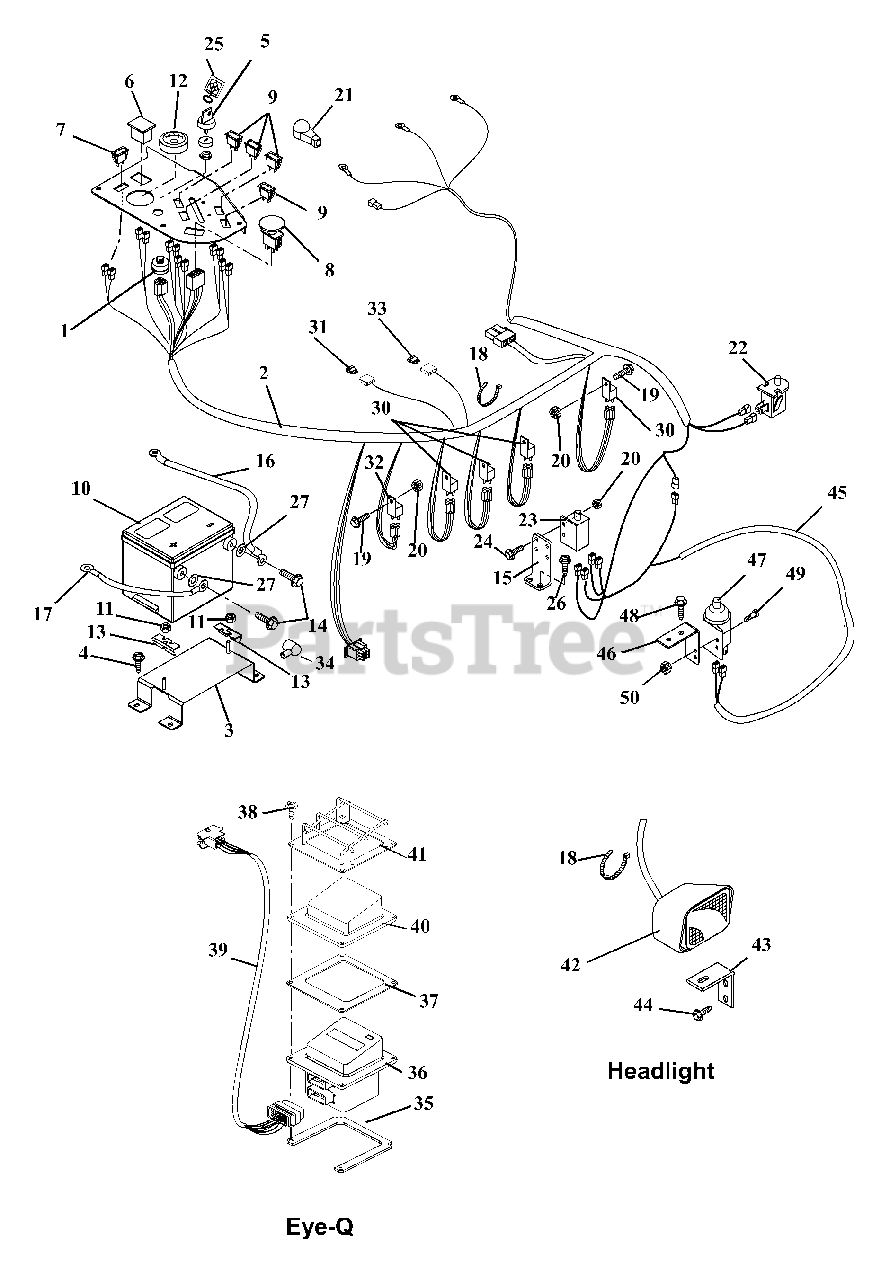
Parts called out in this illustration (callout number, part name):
1	SWITCH, IGNITION
2	HARNESS-MZ HORIZ L/C DIESEL
3	WMT, BATTERY SUPPORT
4	@SCR-TAP .38-16X.75 HWH TR YWZ
5	KEY, W/ SHIELD
6	HOUR METER - DIGITAL
7	SWITCH, 2 POLE/ROCKER
8	SWITCH, CLUTCH
9	LIGHT,INDICATOR
10	BATTERY, GROUP 70 450 CCA 35 A
11	@NUT-LK-TOP-FLG .31-18 YWZC
12	GAUGE, TEMPERATURE
13	BRKT, BATTERY HOLD-DOWN
14	BATT TERMINAL SCREW
15	MOUNT, SAFETY SWITCH
16	CABLE, POS BATT 4 GA X 45
17	CABLE, NEGATIVE BATTERY 49.00
18	CABLE TIE LG 5-1/2
19	@SCR-MCH 10-24X.75 HWH YWZC
20	@NUT-LK-NYL 10-24 W/INSRT YWZC
21	BOOT, EYELET TERMINAL
22	SWITCH- SNAP MTG N.O.
23	SWITCH- DOUBLE POLE N.O./N.O.
24	@SCR-MCH 10-24X.75 HWH YWZC
25	KEY CHAIN
26	@SCR-TAP .25-20X.50 HWH TR YWZ
27	@WSHR-FL-STL.38X.875X.083 YWZC
28	FUSE, ATO 15 AMP
29	DIODE, CONNECTOR SHELL
30	RELAY,SEALED W/DIODE
31	FUSE, ATO 30 AMP
32	Pre-Heat Timer
33	FUSE, ATO 60 AMP
34	BOOT, EYELET TERMINAL
35	SPACER, ENCLOSURE MTG. (BTM)
36	ASSY, EYE-Q
37	GASKET-EYE Q
38	SCR-MCH 10-24X1.0 SL PAN BLACK
39	HARNESS - EYE-Q
40	GUARD, ELEMENT
41	GUARD, VINYL EYE-Q
42	HEADLIGHT
43	BRACKET, HEADLIGHT MTG
44	@SCR-TAP .38-16X.50 HWH TR YWZ
45	HARNESS, WIRE ADAPTER CE
46	MOUNT - SWITCH
47	SWITCH-SINGLE POLE N.O.W/COVER
48	@SCR-TAP .31-18X.50 HWH TR YWZ
49	@SCR-MCH 10-24X.75 HWH YWZC
50	@NUT-LK-NYL 10-24 W/INSRT YWZC
